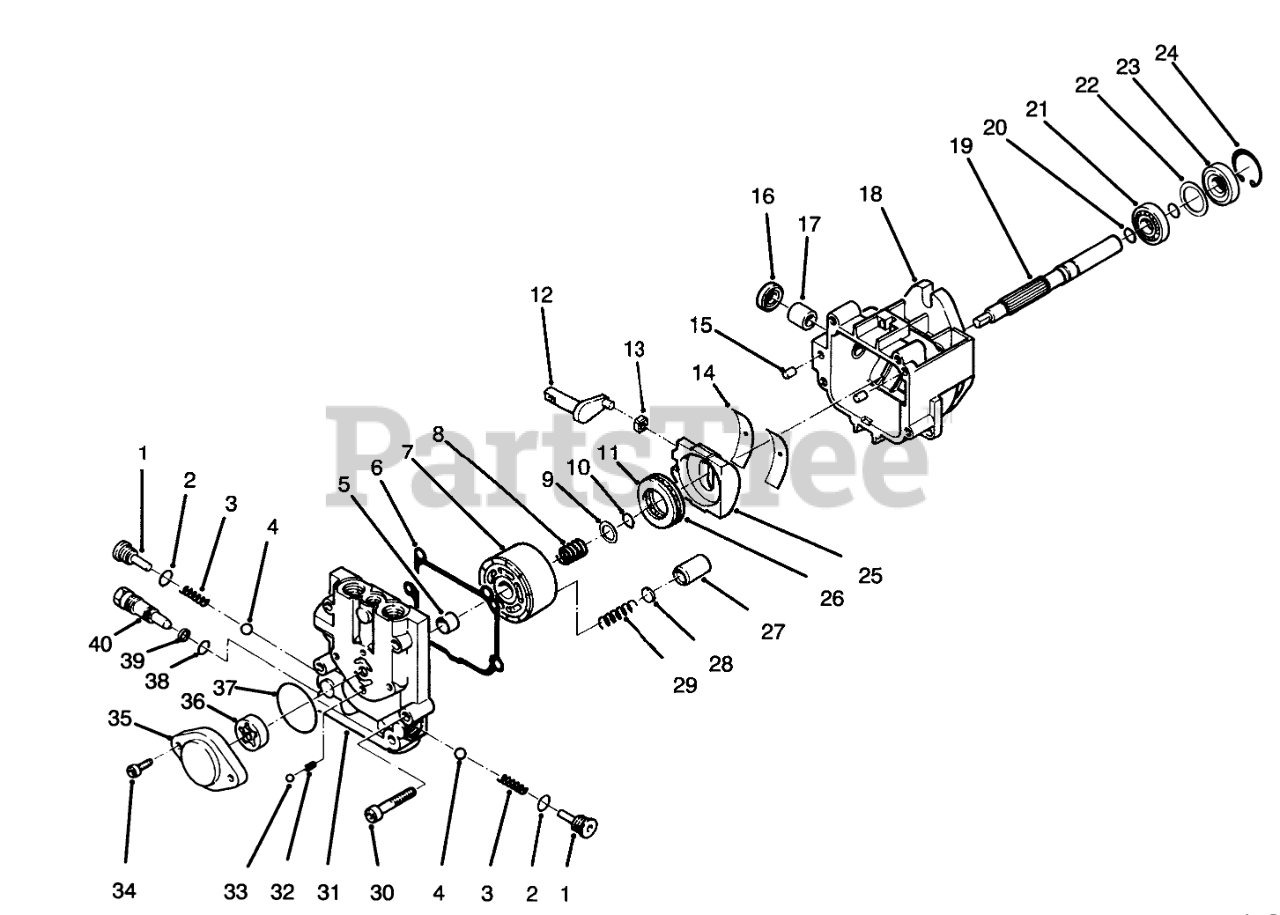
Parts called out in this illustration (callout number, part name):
1	Check Valve Kit (Incl. Ref. #2-4)
2	Seal-O-Ring
3	Spring
4	Ball
5	Journal-Bearing
6	Gasket-End Cap
8	Spring
9	Washer
10	Ring-Retaining
11	Plate-Thrust
12	Arm-Trunnion
13	Guide-Slot
14	Cradle-Bearing
15	Pin
16	Seal-Lip
17	Journal-Bearing
19	Shaft
20	Ring-Retaining
21	Bearing-Ball
22	Spacer
23	Seal-Lip
24	Ring-Retaining
25	Swashplate Assembly
26	Roller-Thrust
27	Piston
28	Washer-Thrust
29	Spring-Piston
30	Screw
32	Ball
33	Spring
34	Screw
35	Housing-Charge Pump
36	Gerotor Assembly
37	Seal-O-Ring
38	Seal-O-Ring
39	Ring-Back-Up
40	Valve-Bypass
